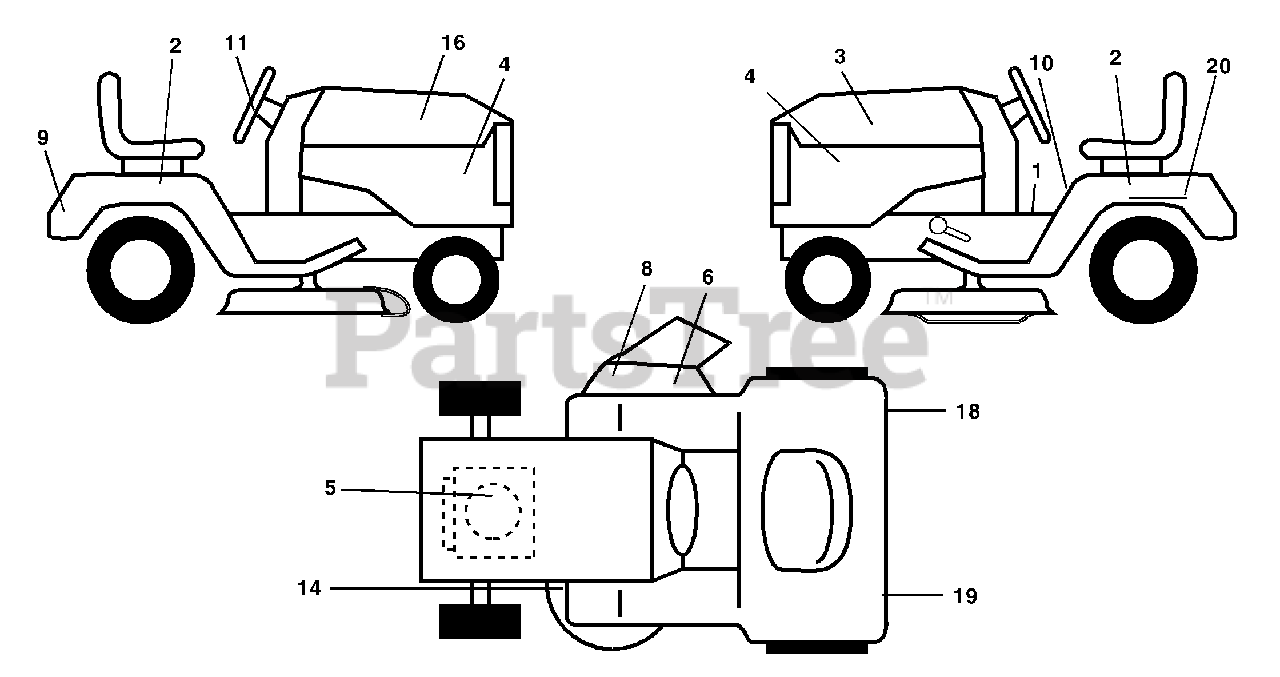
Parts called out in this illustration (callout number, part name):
2	Decal Fender Side
3	Decal Hood LH
4	Decal Side Panel Logo
5	Decal HP Engine
6	Decal Deck "B" 42"
8	Decal Warning Mult-Language
9	Decal Fender Logo
10	Decal Fender Danger E/F
11	Decal Ins Strg Whl
14	Decal V-Belt Schematic
16	Decal Hood Rh
18	Decal Fender Reflector RH
19	Decal Fender Reflector LH
20	Decal Bat Dan/Psn
